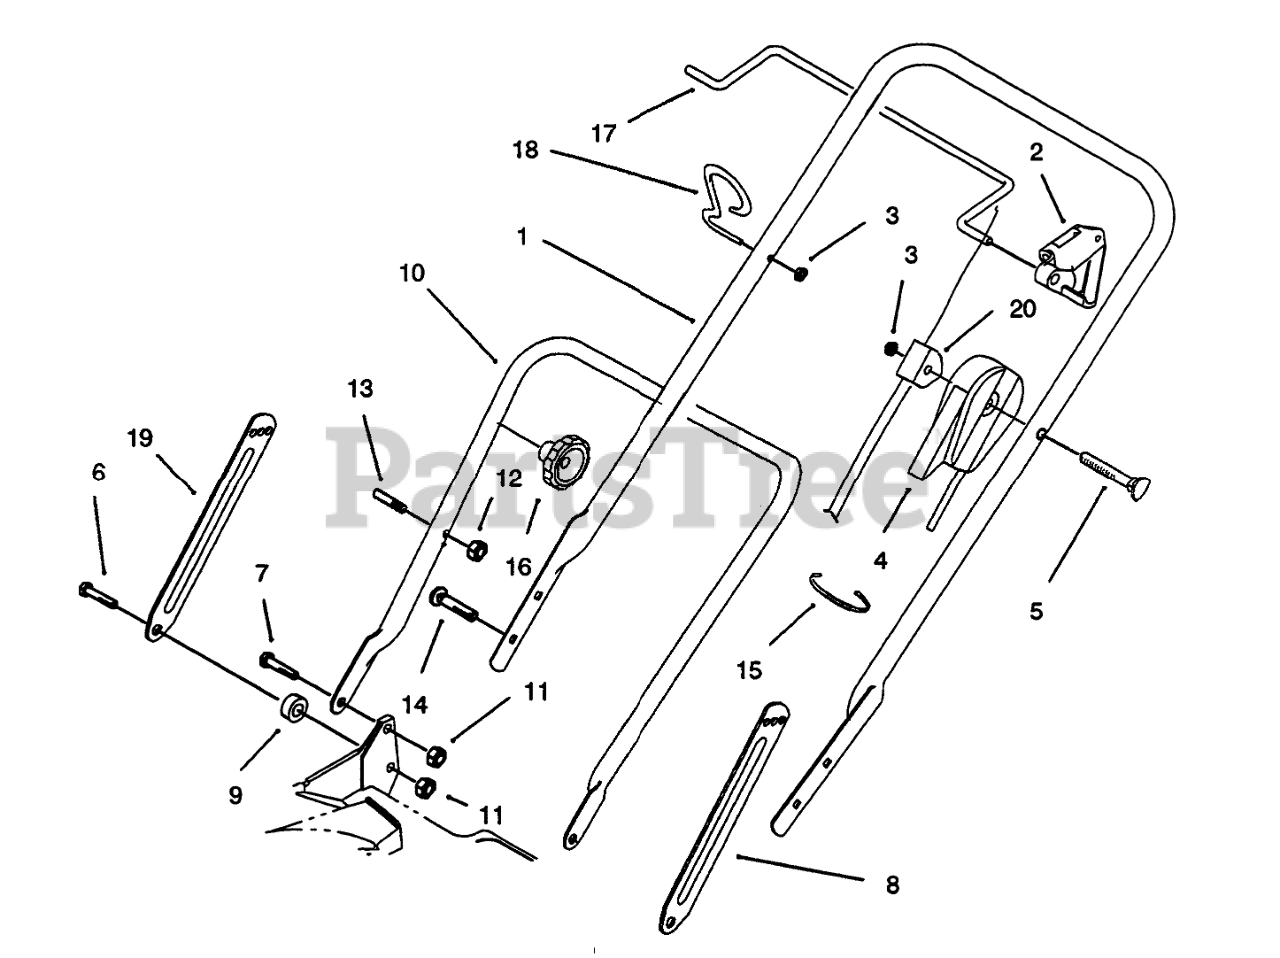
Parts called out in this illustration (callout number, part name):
1	UPPER HANDLE
2	STOP-PIVOT
3	NUT-LOCK, NI
4	THROTTLE CONTROL
5	SCREW-HANDLE
6	SCREW-SHOULDER
7	SCREW-SHOULDER
8	LH HANDLE LATCH
9	SPACER
10	LOWER HANDLE ASM
11	NUT-LOCK, NI
12	NUT-LOCK, NI
13	HANDLE PIN
14	SCREW-HANDLE
15	TIE-CABLE
17	Bar-Control
18	GUIDE-ROPE
19	RH HANDLE LATCH
20	BRAKE CONTROL
